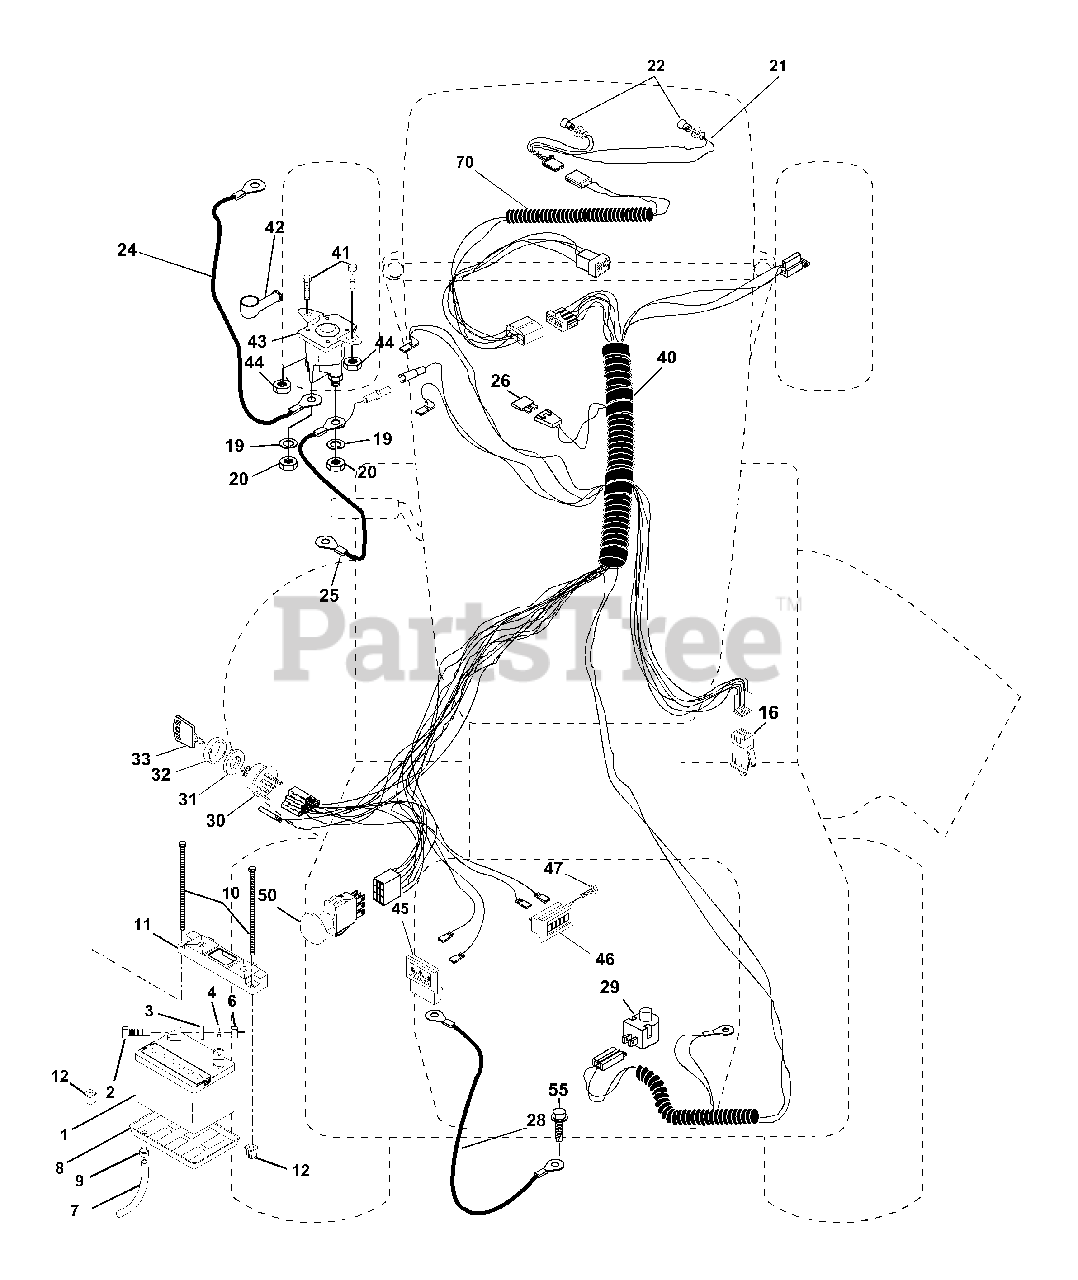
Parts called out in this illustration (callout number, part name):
1	Battery 12 Volt 35 AMP Wet
2	Bolt Hex Hd 1/4-20unc X 3/4
3	Washer 9/32 X 5/8 X 16 Ga.
4	Washer Lock Hvy Helical 1/4
6	Nut Fin Hex 1/4-20 Unc
7	Tube Plastic 46" Front
8	Tray, Battery 7.80 x 5.25 Blk
9	Clamp Hose Olive
10	Bolt BTR FRT 1/4-20 x 7.5 zinc
11	Holddown Battery, Dash mount
12	Nut, Push Nylon 1/4 battery FRT
16	Switch Interlock Push-In
19	Washer Lock 1/4
20	Nut Jam Hex 1/4-20 Unc
21	Harness Asm Light W/4152j
22	Bulb Light #1156
24	Cable Battery 6 Ga 11" red
25	Cable Battery 6 Ga 22" w/16W
26	Fuse 30 AMP Auto Green
28	Cable Ground 6 Ga 21" black
29	Switch Plunger Nc Gray
30	Switch Ign 4 pos w/lights
31	Nut Ignition
32	Cover Sw Ignition
33	Key Ign Modleded Generic
40	Harness Ign. Elec. HM P/L
41	Bolt Blk Fin Hex 1/4 - 20 x 1/2
42	Cover Terminal Red
43	Solenoid
44	Nut Keps Hex 1/4-20 Unc
45	Ammeter, retangular 15 amp
46	Meter, Hour
47	Screw 10-24 x 1/2 Black
50	Switch PTO 3 PTD Black
55	Screw THDROL 5/16-18 x 1/2 TYT
70	Harness, Eng.
